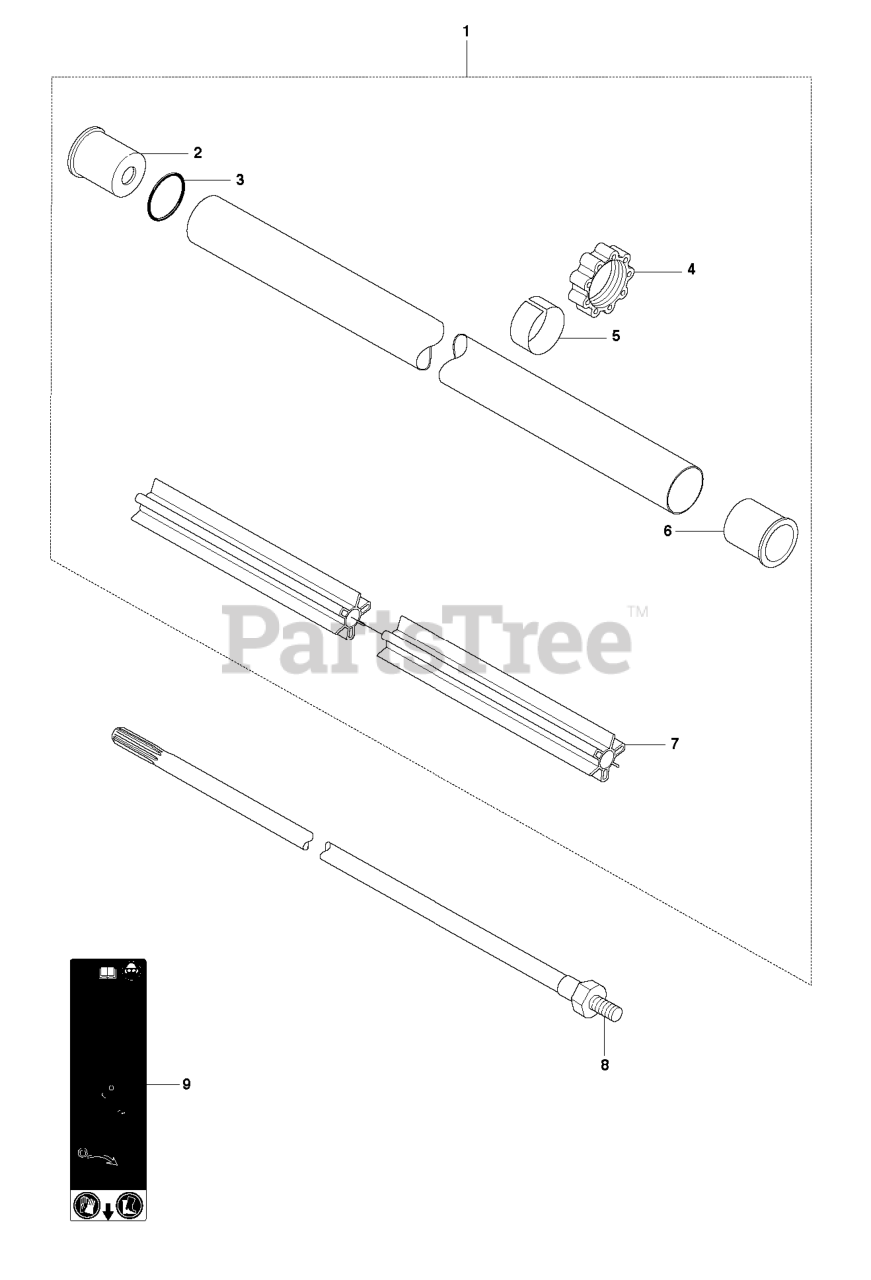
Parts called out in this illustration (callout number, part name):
1	RP DRIVE SHAFT TUBE
1	TUBE
2	SPACER SLEEVE
4	MOVEMENT LIMITER
5	%BAND
6	SPACER SLEEVE
7	GUIDE
8	SHAFT
8	DRIVE SHAFT
9	WARNING DECAL
